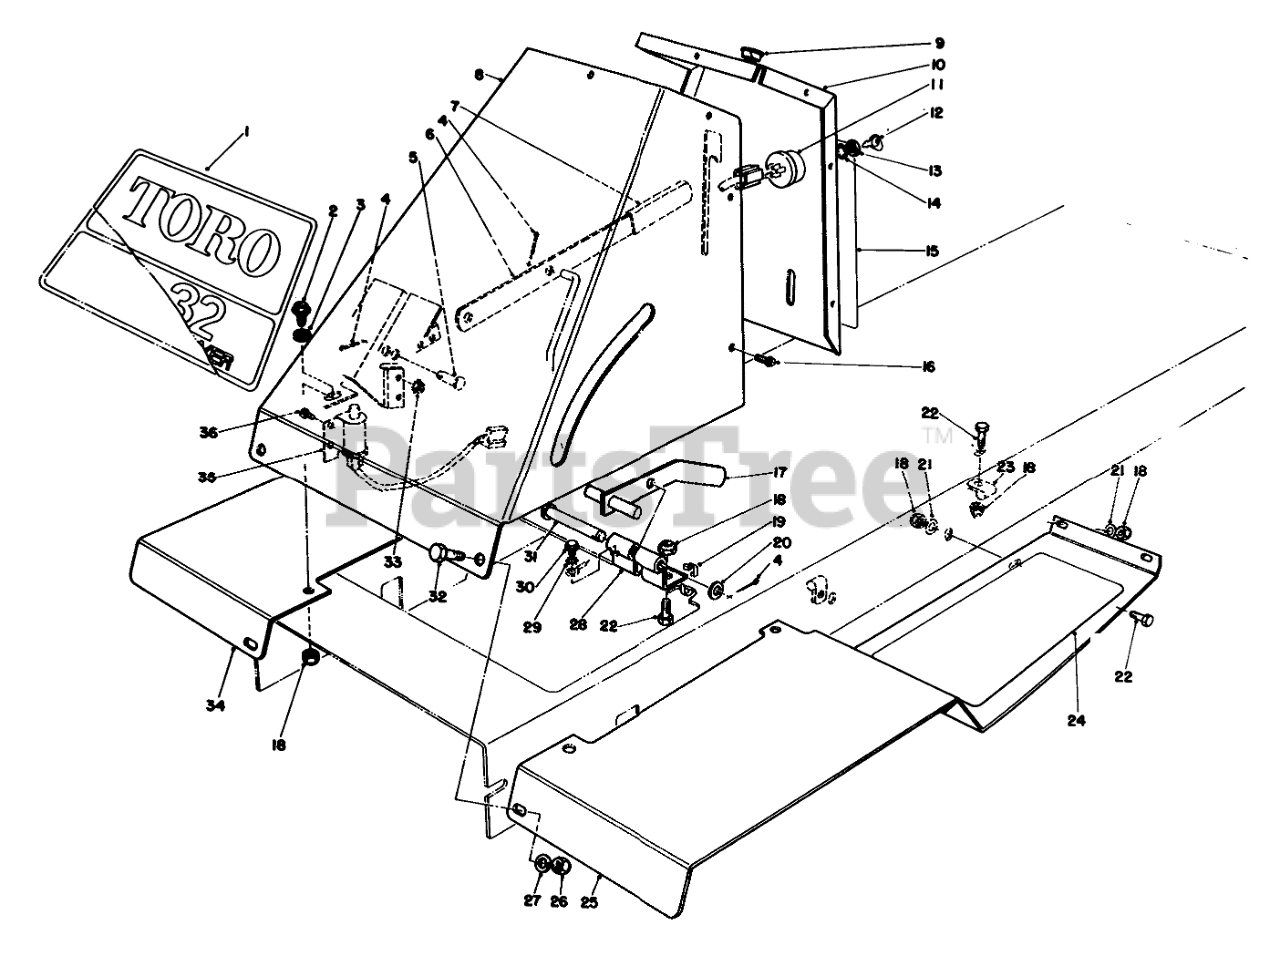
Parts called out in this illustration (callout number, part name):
1	Decal-Toro 832
2	SCREW-SHOULDER
3	SPACER
4	PIN-COTTER
5	PIN-CLEVIS
6	ENGAGE LEVER B
8	Tower-Front
9	NYLINER #12L1-FF TYPE 7
10	REAR TOWER R
11	SWITCH-STARTER
12	Key
13	NUT-HH
14	WASHER-TOOTH, INTERNAL
15	DECAL-ENGAGE
16	SCREW-HWHTF
17	PARKING BRAKE WA B
18	NUT-LOCK, NI
19	TIE-CABLE
20	WASHER-FLAT
21	WASHER-PLAIN
22	SCREW-HH
23	CLAMP
24	FOOT TREAD L.H.
25	Footrest-LH
26	NUT-LOCK, CONE
27	WASHER-FLAT
28	Bracket-Parking Brake
29	WASHER-LOCK, INTERNAL
30	SCREW-HHF
31	PIN-CLEVIS
32	SCREW-HH
33	NUT-KEPS
34	Footrest-RH.
35	DECK INTERLOCK SWITCH
36	10-24 X 1/2 FIL HD MS
